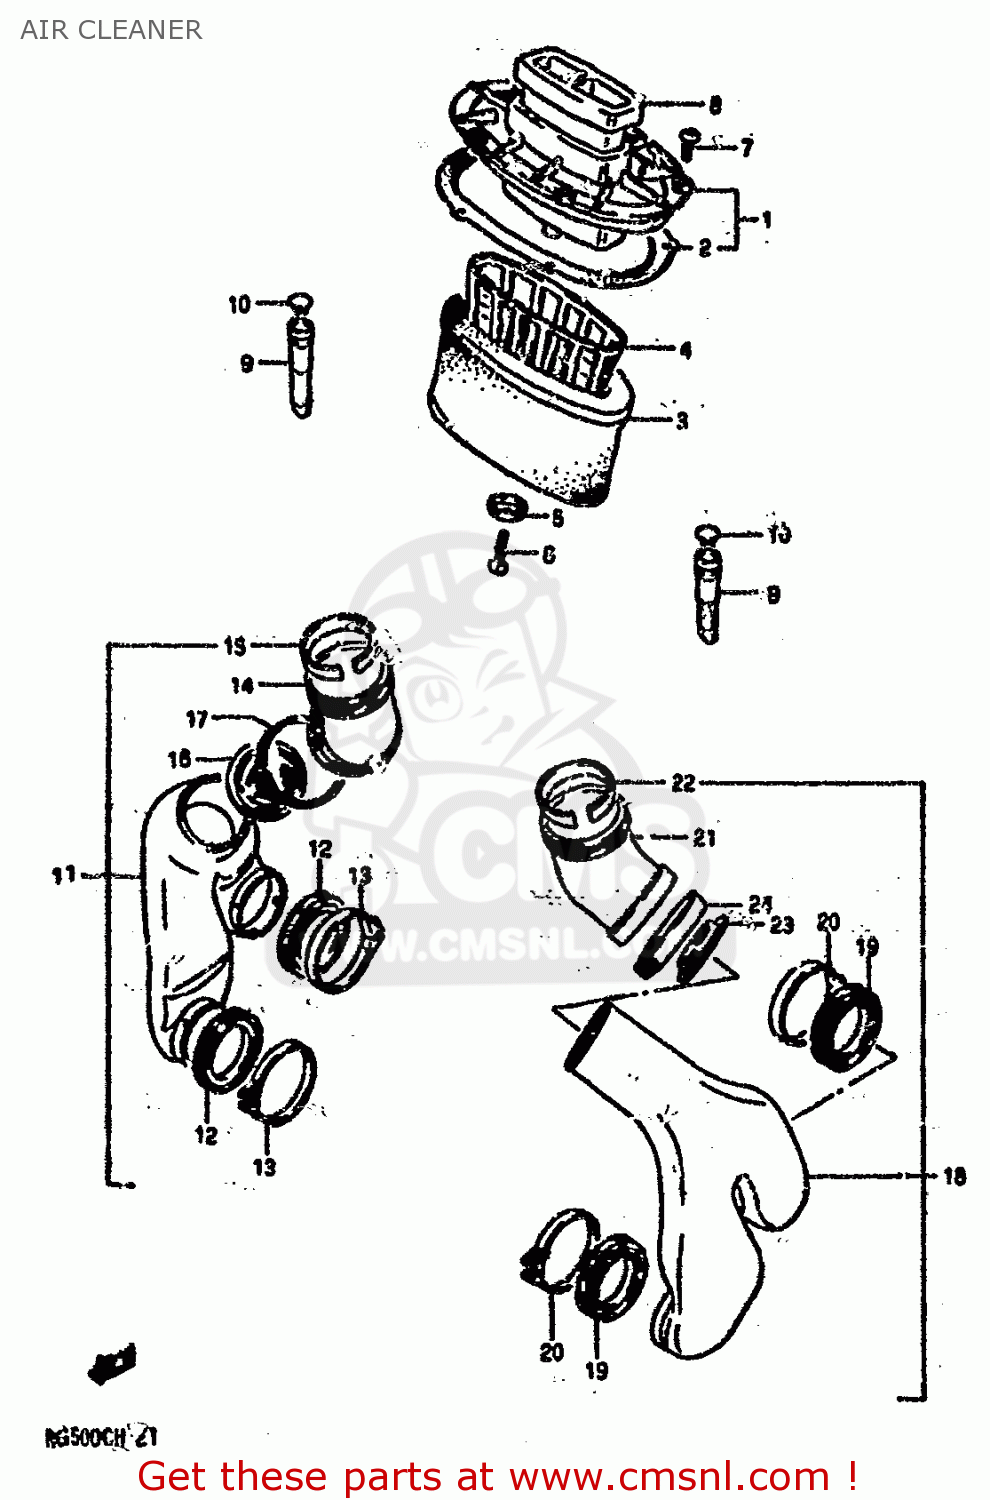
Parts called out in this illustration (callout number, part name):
1	CAP
2	GASKET (NAS)
3	FILTER,AIR
4	HOLDER
5	HOLDER,FILTER
6	SCREW
7	SCREW
8	TUBE,INLET
9	HOSE,DRAIN
10	CLIP
11	OUTLET TUBE,RH
12	RING
13	CLAMP
14	JOINT
15	RING,JOINT
16	TRAP
17	CLAMP
18	OUTLET TUBE,LH
19	RING
20	CLAMP
21	JOINT
22	RING,JOINT
23	TRAP
24	CLAMP
